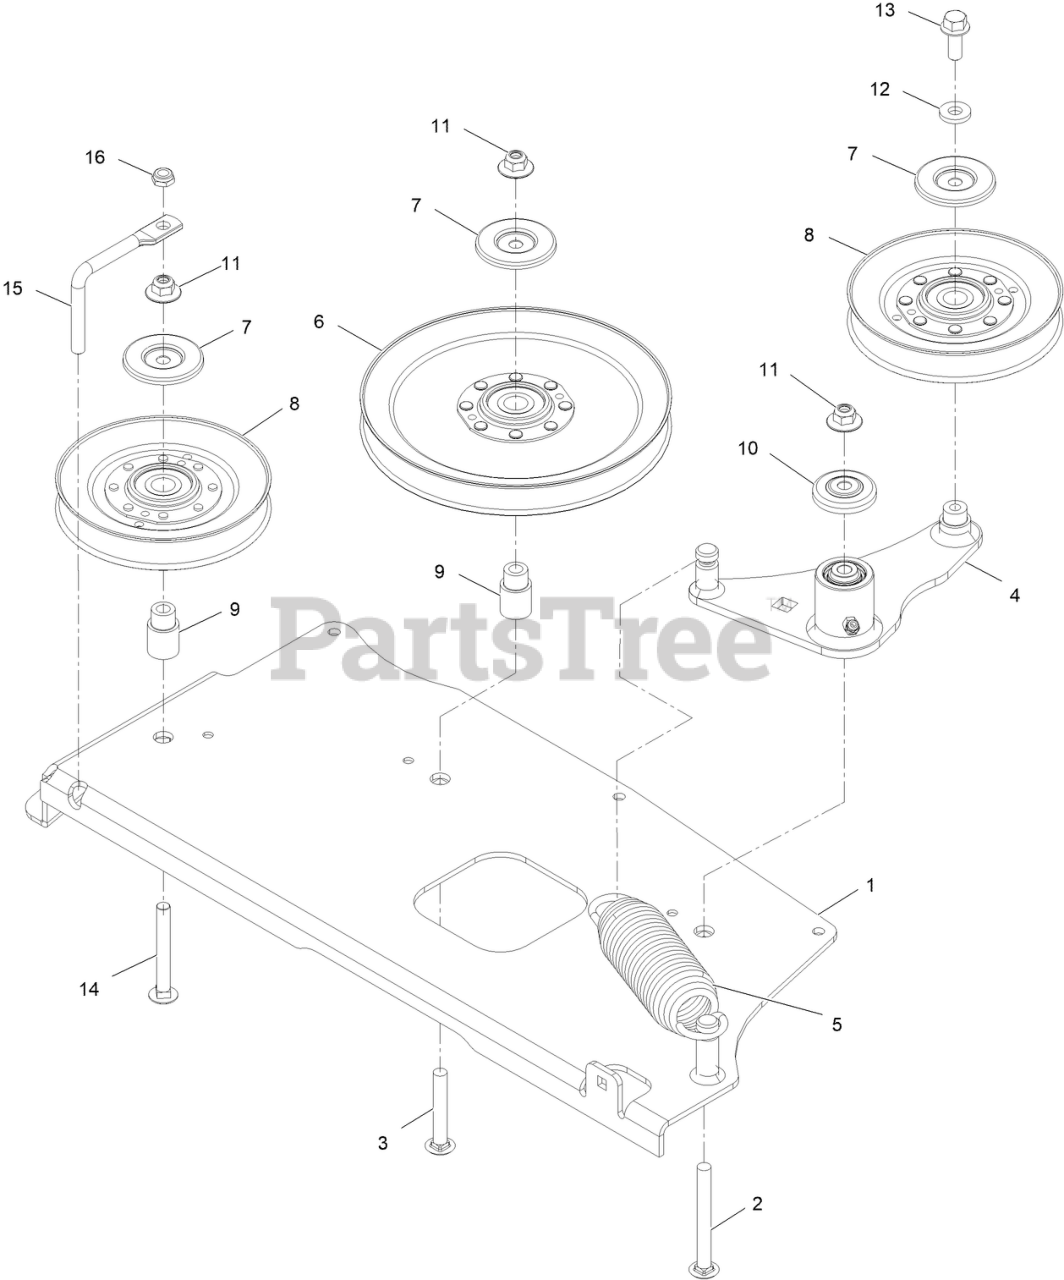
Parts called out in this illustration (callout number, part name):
1	MOUNT-IDLER
1	FITTING-LUBE, 45 DEG
2	BOLT-SHOULDER, CARRIAGE 3/8-16 X 3 1/2
3	SCREW-CARR
3	RING-SNAP
4	IDLER ARM ASM
4	BEARING-SPHERICAL
5	SPRING-EXTENSION
6	SEAL-LIP, DOUBLE
6	IDLER-V
7	SEAL-LIP, SINGLE
7	SHIELD-DUST
8	IDLER V
9	STANDOFF-IDLER
10	GUARD-TOP
11	Nut-Nyloc 3/8-16 Flg
13	SCREW-HHF
14	SCREW-CARR
15	GUIDE-BELT
